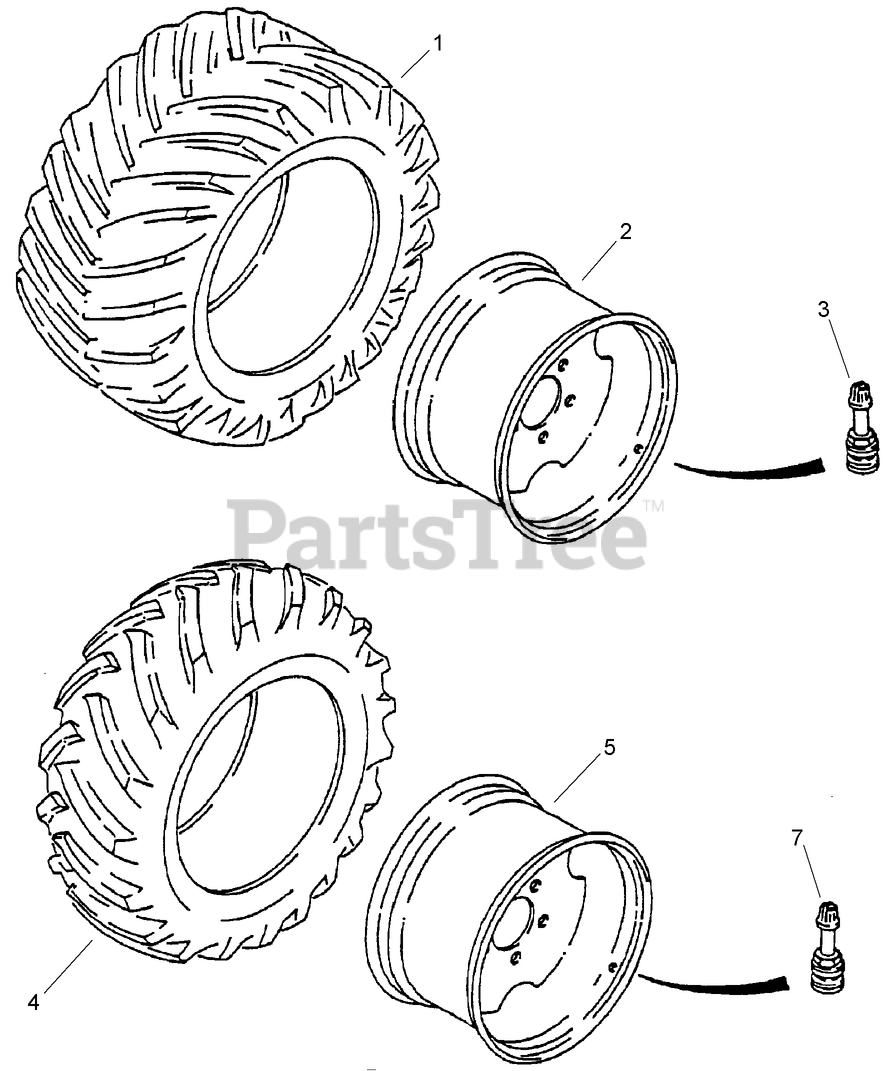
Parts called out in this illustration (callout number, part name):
1	TIRE - 23 x 10.50 x 12, 4 PR, All Traction, Super Terra Grip (purchase locally)
1	TIRE - 26 x 12 x 12, 8 PR, All Traction, Super Terra Grip (purchase locally)
2	WHEEL - Rim, 8.50 x 12 inch, Used with 10.50 x 12 Tire
2	WHEEL - Rim, Used with 26 x 12 x 12 Tire
3	STEM-Valve
4	TIRE - 26 x 12 x 12, 4 PR, Hi-Flotation, Super Terra Grip (purchase locally)
5	WHEEL - Rim, Used with 26 x 12 x 12 Tire
7	STEM-Valve
